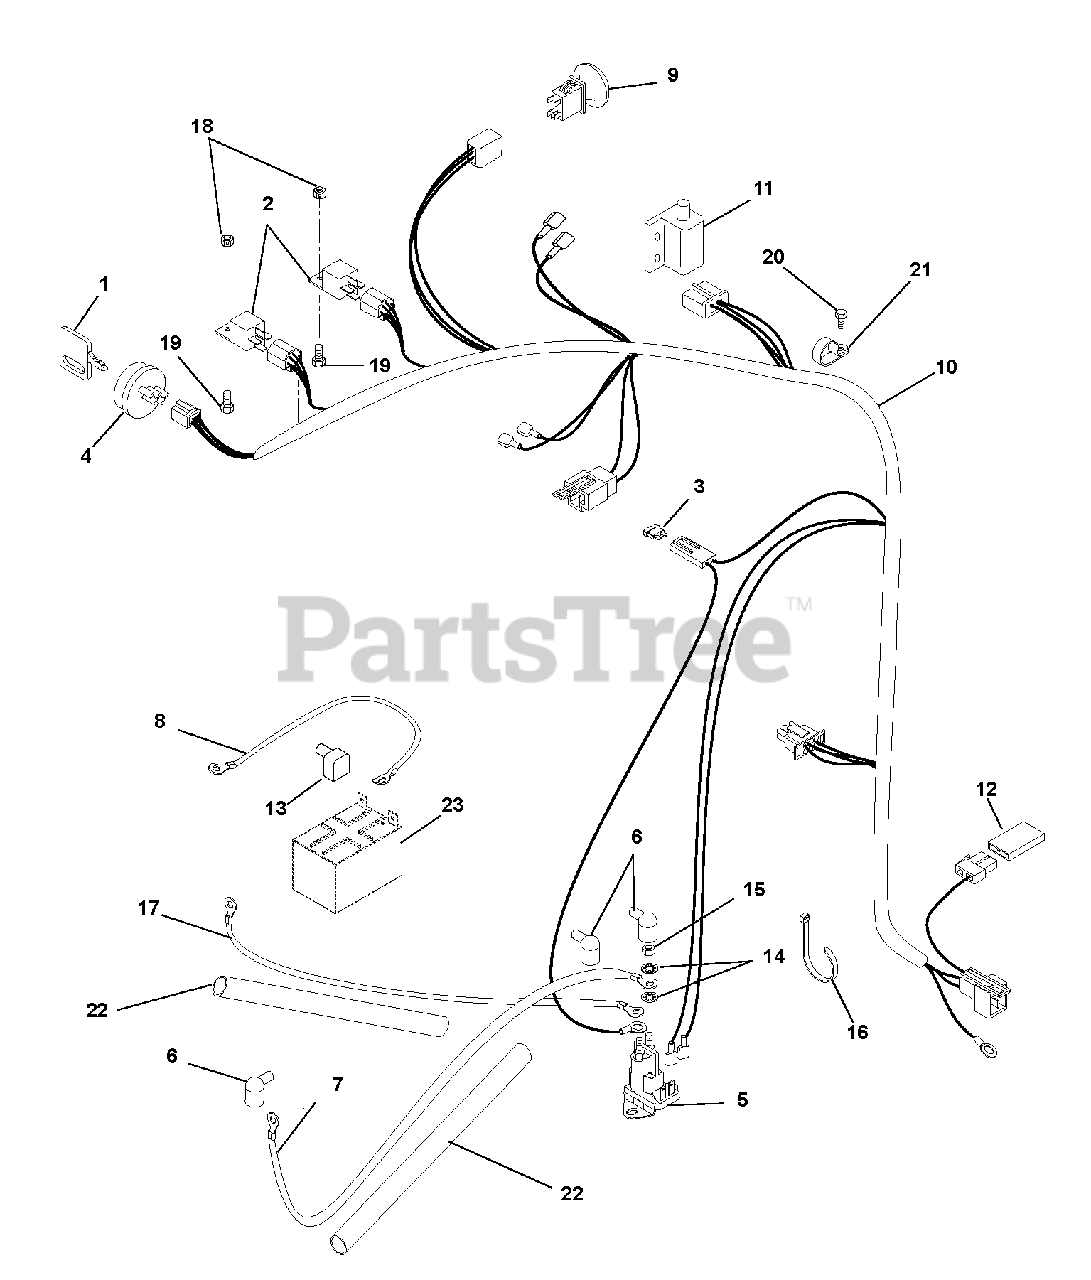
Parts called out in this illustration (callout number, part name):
1	Key with Cap
2	Relay
3	Fuse, 30 AMP
4	Key Switch
5	Solenoid
6	Boot, Eyelet Terminal
7	Starter Cable
8	Cable, Ground .25 x 13.00 x .31
9	Switch, Clutch With Retainer
10	Harness, ZTXL/ZoomXL
11	Switch, Double Pole N.O. / N.O.
12	Diode, Connector Shell
13	Insulator
14	Washer, Locking .31
15	Nut, Jam .31-24
16	Cable Tie
17	Starter Cable
18	Nut, Locking Nylon With Insert 10-24
19	Screw, Hex Washer Head Machine 10-24 x .75
20	Screw, Tapping Hex Washer Head Thread Rolling .38-16 x .50
21	Clamp, Cushioned Steel .75
22	Sleeve, Anti-Abrasion
23	Battery, 12V, 215 CCA GEP
